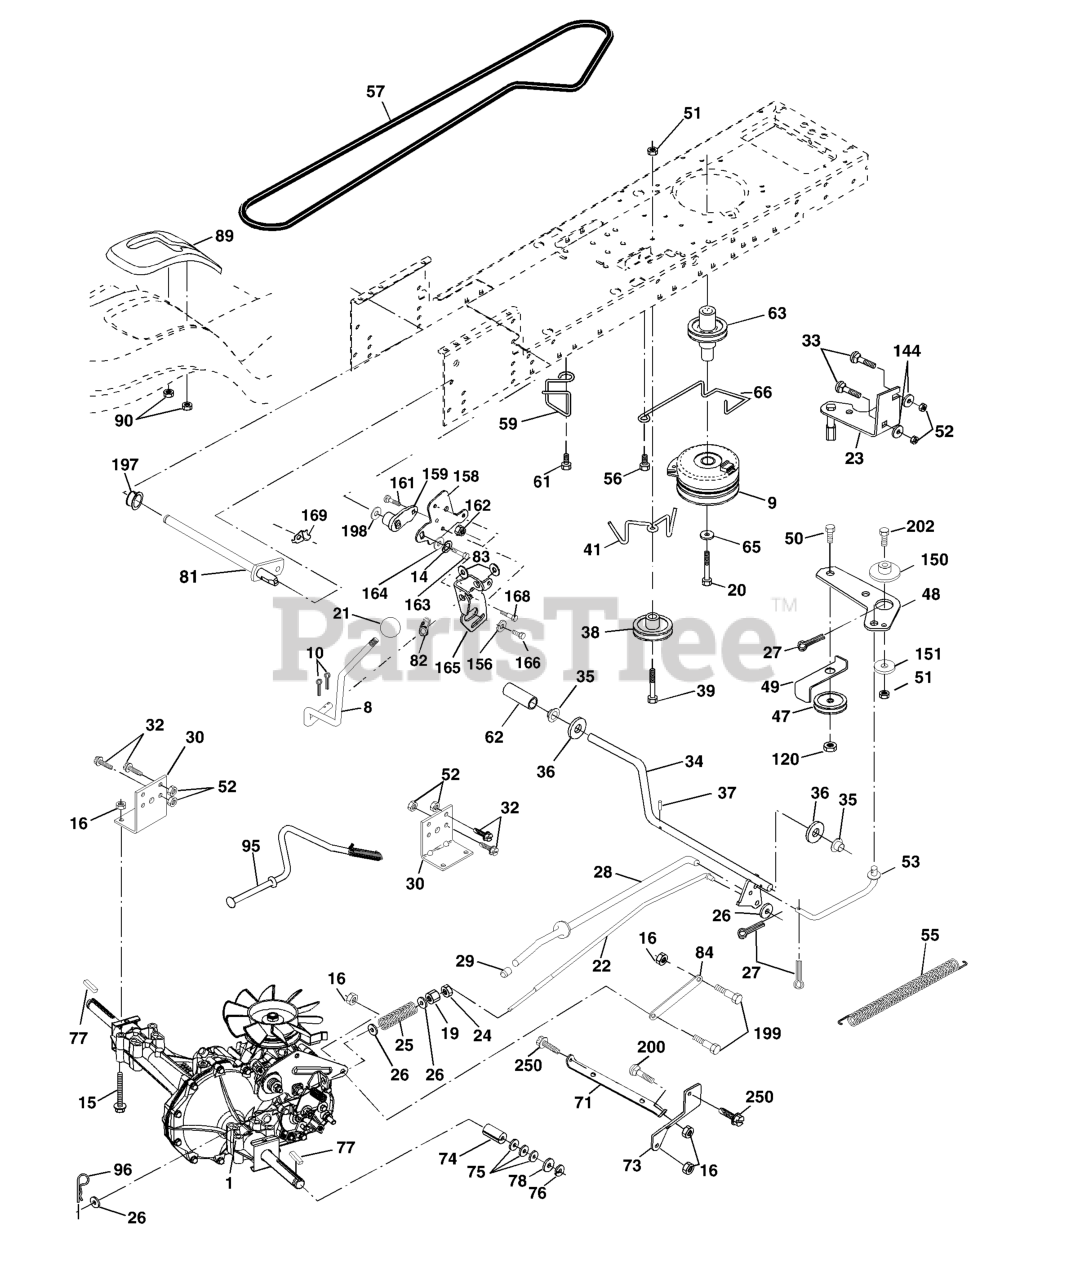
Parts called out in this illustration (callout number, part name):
8	ROD SHIFT FENDER ADJUST STLT
9	ELECTRIC CLUTCH
10	PIN COTTER
14	LOCKWASHER
15	BOLT HEX 5/16-18 GR 5
16	NUT.71038.31-18.HEX.NYLOCK
19	NUT
20	BOLT HEX
21	KNOB.DELUXE.(PISTOL.GRIP).BLAC
22	ROD BRAKE HYDRO
24	NUT
25	SPRING ROD LT
26	WASHER
27	COTTER PIN
28	ROD, PARKING BRAKE
29	PLUNGER CAP
30	BRKT, TRNSXLE MNT 20"
32	BOLT
33	RP BOLT 5/16-18 X3/4 ZN/YEL GR
34	SHAFT, FOOT PEDAL
35	BEARING.NYLON
36	WASHER LT
37	DRIVE PIN
38	PULLEY IDLER COMPOSITE
39	BOLT
41	KEEPER, BELT IDLER
47	IDLER PULLEY
48	BELLCRANK, CLUTCH
49	RETAIN BELT
50	BOLT
52	LOCKNUT
53	LINK, CLUTCH LT
55	SPRING, RETURN LT
56	SCREW.3/8-16
57	DRIVE BELT, LTH & YTH TRACTORS
59	KEEPER, BELT CENTER
61	SCREW 3/8-16X.875
62	PEDAL COVER T
63	PULLEY, ENGINE
65	LOCKWASHER
66	KEEPER BELT ENGINE
71	STRAP TORQUE LH HYDRO
73	STRAP TORQUE RH HYDRO
74	SPACER AXLE
77	SQUARE KEY
81	SHAFT ASM CROSS TAPERED
82	SHIFT SPRING
83	WASHER
84	LINK TRANSAXLE
89	SHIFT CONSOLE
90	NUT.PUSH.3/16
95	CONTROL ASM. BYPASS HYDRO
96	RETAINER M
120	NUT LOCK FLG 3/8-16 UNC
144	Washer 11/32 x 5/8 x 16 Ga.
150	SPACER, RETAINER
151	WASHER 12/32X2X10GA
156	WASHER.SRRTD.5/16
158	BRACKET
159	HUB
161	BOLT
162	NUT.CROWNLOCK.1/4
163	BOLT
164	Washer 5/8 x .281 x 10 Ga
165	RP BRACKET
168	BOLT.SHOULDER.5/16-18X
169	PLATE.FASTENING.CROSS.SHAFT
197	NYLINER SNAP 5/8" ID
198	WASHER.NYL.7/8IDX.105"HYD CR
199	BOLT SHOULDER 5/16-18 UNC
200	BOLT
250	SCREW 3/8-16X3/4
